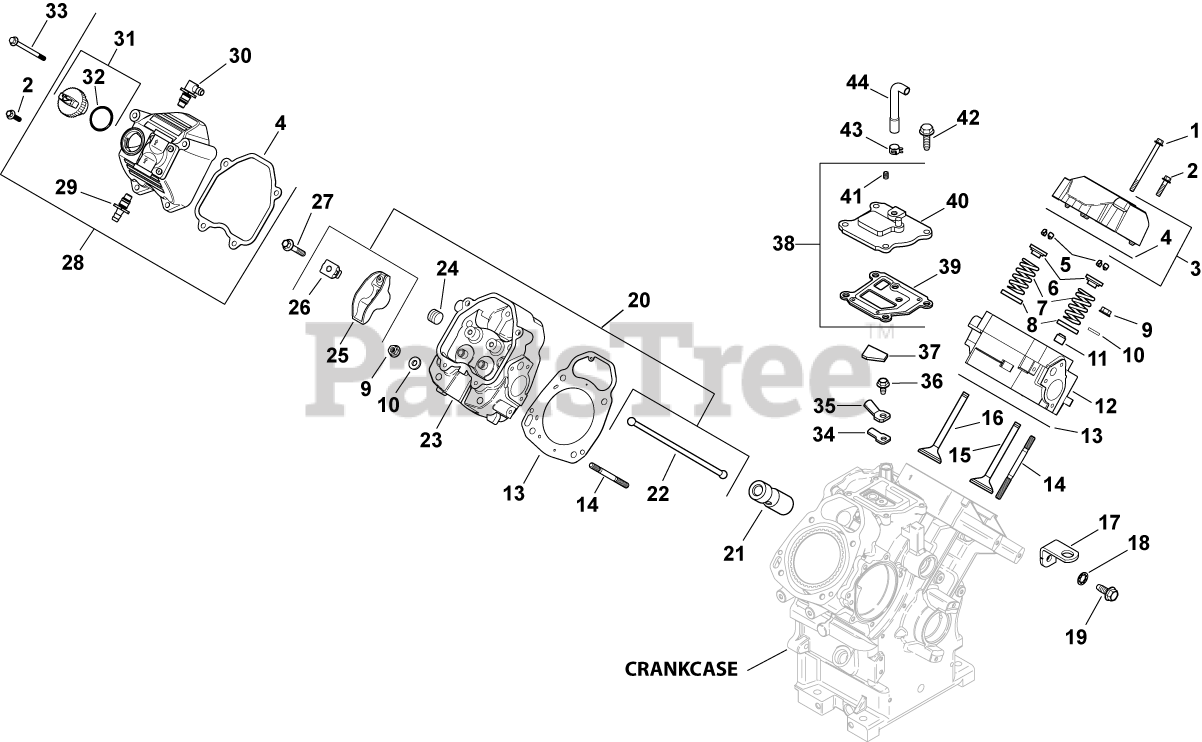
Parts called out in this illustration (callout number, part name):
1	SCREW, FLG M6X1.0X55
2	SCREW - USE 25 086 124-S
3	KIT, ROCKER COVER
4	GASKET, VALVE COVER
5	KIT, RETAINER
6	RETAINER, VALVE SPRING - USE 25 173 28-S
7	SPRING, VALVE
8	RETAINER-USE 235011-S
9	NUT, FLG M8X1.25
10	WASHER, FLAT 5/16"
11	SEAL, VALVE STEM - (#2503214S)
12	KIT,CYLINDER HEAD #1
13	KIT, CYLINDER HEAD GASKET
15	VALVE, INTAKE (STD)
16	VALVE, EXHAUST (STD) - USE 32 016 01-S
18	WASHER, INT TOOTH LOCK 1/4"
19	SCREW,FLG THD FRM M6X1.0X16-(#25086397S)
20	KIT, VALVE TRAIN
21	LIFTER, HYDRAULIC VALVE-USE 25 351 10-S
22	ROD, PUSH
23	KIT,CYLINDER HEAD #2
24	PLUG, PIPE
25	ARM, ROCKER
26	PIVOT, ROCKER ARM
27	SCREW, ROCKER ARM PIVOT-USE M-640034-S
28	KIT, FUEL PUMP/ROCKER COVER
29	KIT, STRAIGHT FITTING
30	KIT, 90 DEG. FITTING
31	CAP ASSY, OIL FILL (YELLOW)
32	O-RING-USE 24 153 32-S
33	SCREW, FLG M6X1.0X80
34	REED, BREATHER
35	RETAINER, REED
36	SCREW, FLG THD FRM M5X.8X10
37	FILTER, BREATHER-USE 24 050 11-S
38	KIT, BREATHER ASSEMBLY
39	GASKET, BREATHER-USE 24 041 67-S
40	COVER, BREATHER -USE 24 033 01-S
41	PLUG, CTSK PIPE 1/8"
42	SCREW,FLG THD FRM M6X1.0X20-(#25086396S)
43	CLAMP, BAND SPRING HOSE-(#2523737S)
44	HOSE ASSEMBLY, BREATHER
2401602-S	VALVE, EXHAUST (.25)
2401702-S	VALVE, INTAKE (.25)
6603205-S	SEAL, VALVE STEM - (#2503214S)
